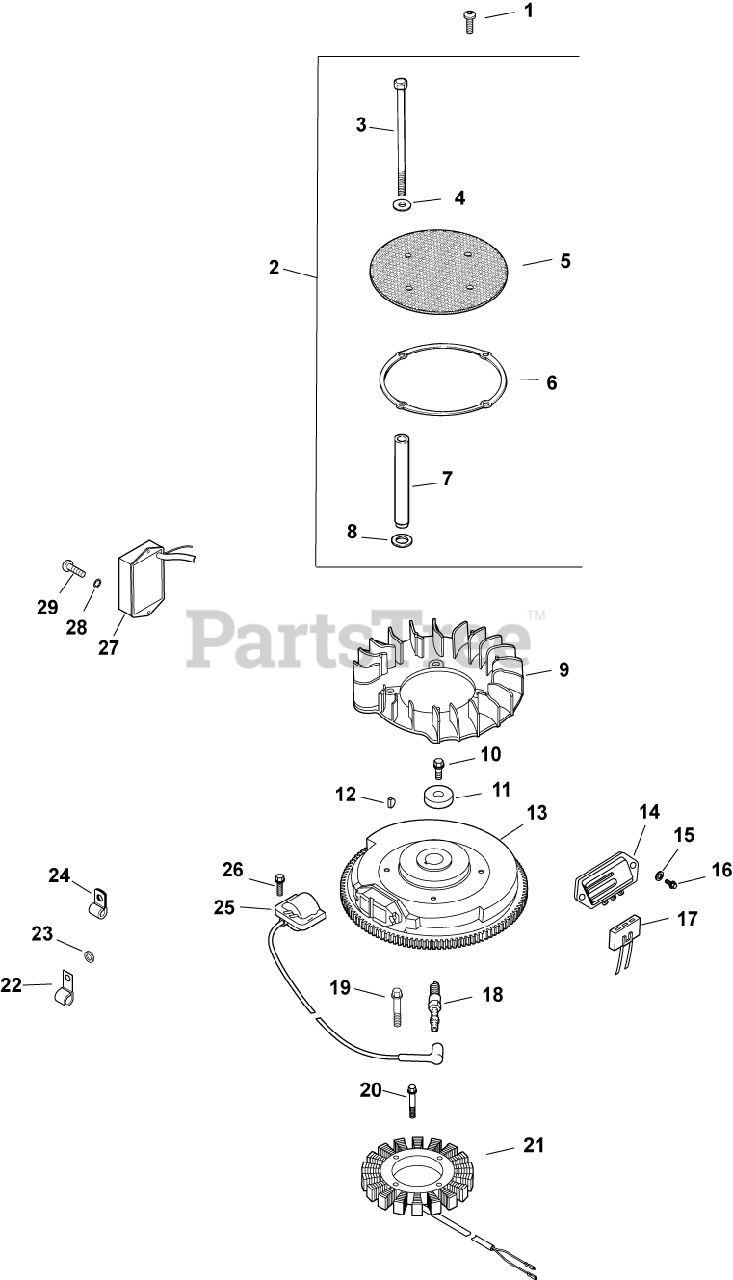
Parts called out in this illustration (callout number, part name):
1	SCREW, SOCKET TRUSS HD CAP
2	KIT, CHOPPER SCREEN
3	SCREW, CAP M6X1.0X99.5
4	WASHER, FLAT 1/4" (O.D. 5/8")
5	SCREEN, GRASS-USE 24 162 41-S
6	RING, SUPPORT USE 25 141 08-S
8	WASHER, SPRING 10 MM
10	SCREW, FLG M10X1.5X45 - (#25086361S)
11	WASHER, FLAT 13/32"
12	KEY, 3/16" X 5/8"
13	FLYWHEEL ASSEMBLY-USE 24 025 58-S
14	REG/RECT-15 AMP (KM)-USE 41 403 10-S
15	WASHER, FLAT 3/16"
16	SCREW, PHL HD #11-16X7/8"
17	CONNECTOR, BODY (KM)-USE 25 155 41-S
18	PLUG, SPARK (PRO SERIES)
19	SCREW, M5X0.8X25 - (#25086402S)
20	SCREW, SKT SET #10-24X1/4"
21	KIT, 15 / 20 AMP STATOR
22	CLIP, TUBE & WIRING (KM)
23	WASHER, FLAT 1/4" (O.D. 1/2")
24	CLIP, CABLE
25	MODULE, IGNITION
26	SCREW, FLG THD FRM M5X.8X20-(#25086399S)
27	MODULE, SPEED ADVANCE -USE 24 755 162-S
28	WASHER, FLAT 1/4" (O.D. 1/2")
29	SCREW, THD FRM M4X0.7X10
2458452-S	MODULE, SPARK ADV -USE 24 584 89-S
